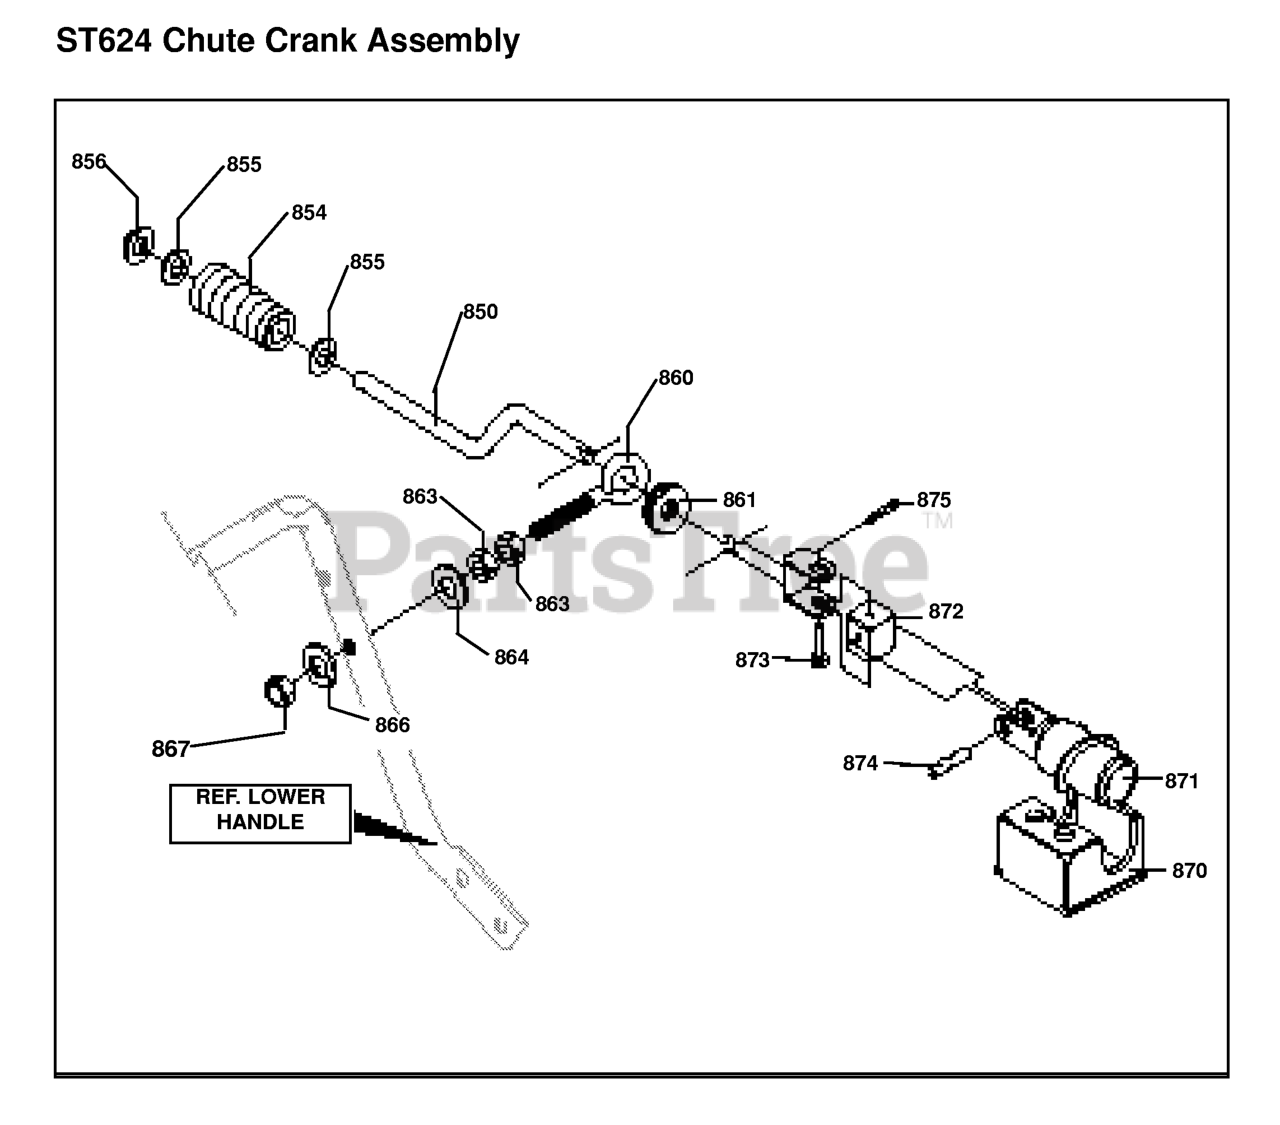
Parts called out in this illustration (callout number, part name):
850	CRANK ASSY W/YOKE
854	HANDLE, CHUTE CRANK
855	WASHER, FLAT .439 X .70 X .05
856	RETAINING RING
864	WASHER, FLAT .406X .81X.
866	WASHER, FLAT .406X .81X.
867	NUT, 3/8-16 HEXNYL
870	BRACKET, WORM MOUNTING
871	WORM GEAR CHUTE ROTATE 585196
872	BLOCK, UNIV
873	PIN, CLEVIS
874	PIN, UNIV JOINT
875	COTTER PIN .06X.50
